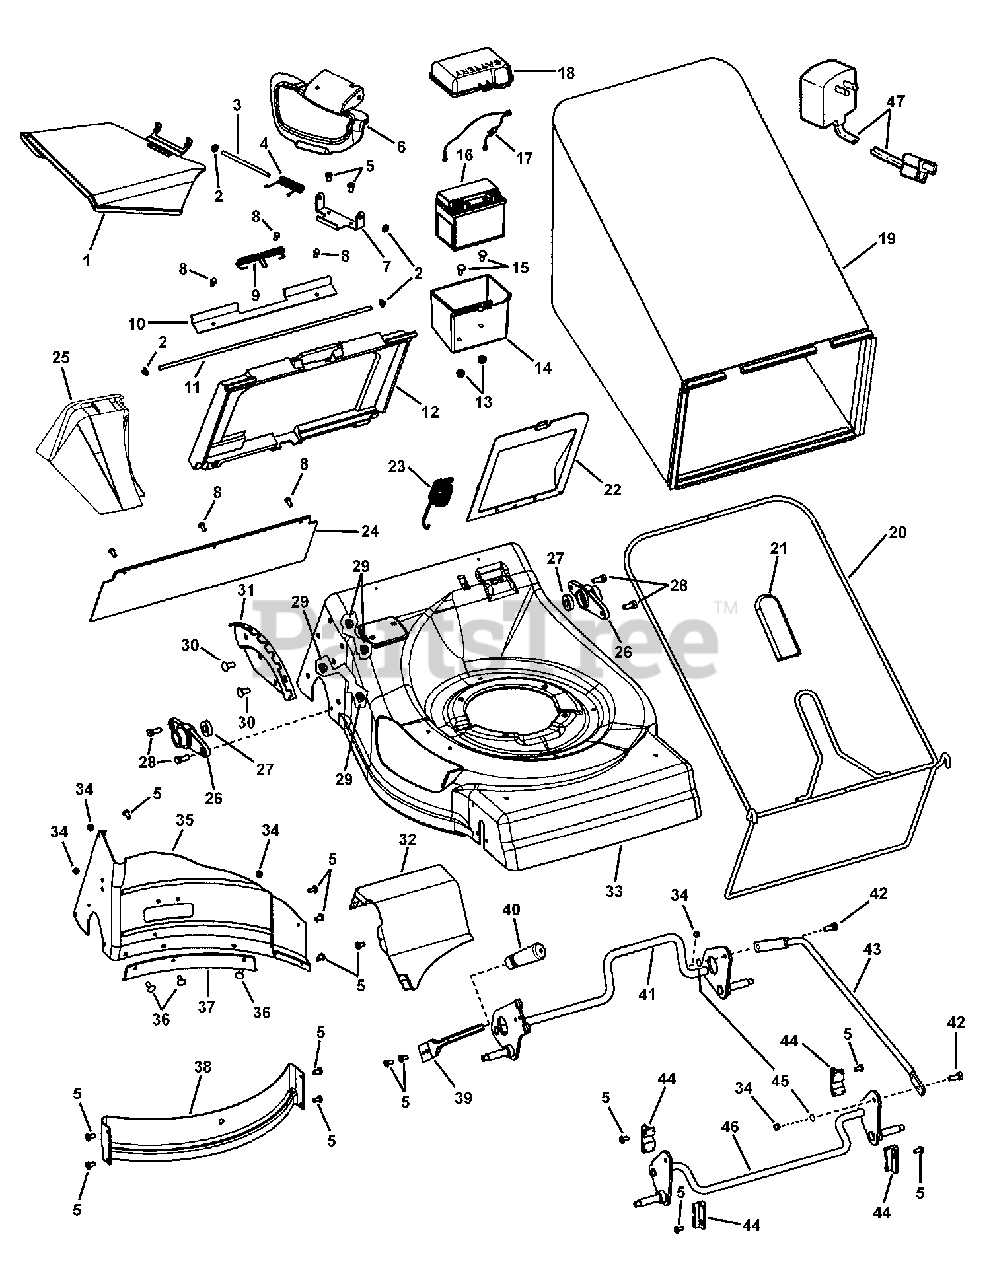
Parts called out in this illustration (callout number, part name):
1	CHUTE, 21" Side Discharge
2	PUSHNUT, 1/4"
3	ROD, Pivot, Mulch Cover
4	SPRING, Torsion, Chute
5	SCREW, 1/4-20 x 11/16 Pan Head Torx, Self-Tap
6	COVER, 21 Mulching
7	BRACKET, Chute Deflector
8	SCREW, #10-24 x 1/2 Hex Washer Self-Tap, SEMS
9	SPRING, Torsion
10	SPACER, Rear Door, 21"
11	ROD, Pivot, Rear Door, 21 RD
12	DOOR, 21 Black
13	NUT, 1/4-20 Hex Flange, Nyloc,YZ
14	BOTTOM, Battery Box- 21 JD WBM
15	BOLT, 1/4-20 x 5/8 Flat Head Square Neck, GR 5
16	BATTERY KIT, 12V, 4.0AH (Includes harness 7015488)
17	HARNESS, Battery
18	TOP, Battery Box - 21 WBM
19	GRASSBAG, 21 Rear Discharge
20	BAG FRAME- 21 RD WBM
21	GRIP, Rectangular (Black)
22	TRANSMISSION COVER, Rear 21"
23	SPRING, Extension, Height-of-Cut Assist
24	DEFLECTOR, Rear, 21 WBM, RD
25	PLUG, Mulching
26	BEARING HOLDER, 21 WBM,RD
27	BALL BEARING, Axle
28	SCREW, 5/16-18 x 3/4 Hex Head Cap, GR 5 YZ
29	NUT, 5/16-18 Hex Flange Lock, GR 5, YZ
30	BOLT, 5/16-18 x 3/4 Round Head Short Square Neck, GR 5, YZ
31	INDEX PLATE, Height-of-Cut, 21 WBM, RD
32	BAFFLE, Right Rear, 21 WBM, RD
33	DECK, 21 Rear Discharge
34	NUT, #10-24 Hex Nyloc
35	BAFFLE, Left Rear, 21 RD, WBM
36	BOLT, #10-24 x 5/8 Flat Head Square Neck, YZ
37	BAFFLE, Extension, 21 RD WBM
38	BAFFLE, Front 21 WBM, RD
39	LEVER, Spring Height-of-Cut
40	GRIP, Height-of-Cut
41	WELDMENT, Rear Crossbar 21 WBM, RD
42	BOLT, Shoulder, #10-24 Thread
43	WELDMENT, Lifter Link, 21 WBM, RD
44	BUSHING, Front, 21"
45	PUSHNUT, 1/4 Black
46	WELDMENT, Front Crossbar 21 WBM, RD
47	CHARGER, Battery 120V/12V
